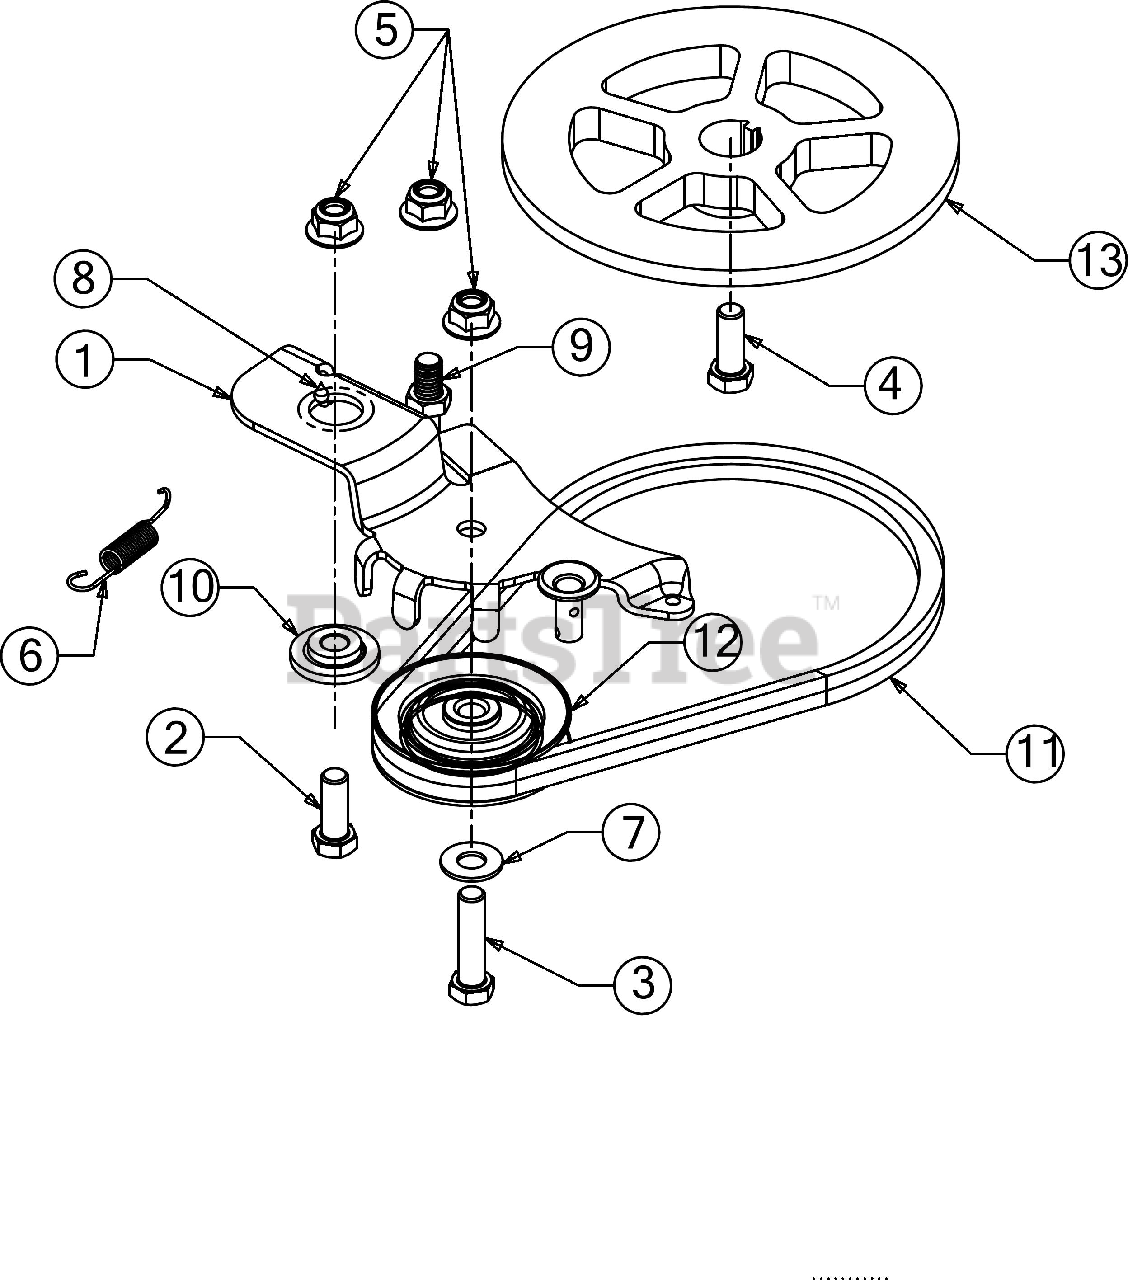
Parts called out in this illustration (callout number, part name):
1	IDLER ASSEMBLY
1	IDLER BRACKET
2	SCREW 3/8-16 X 1 GR5
3	SCREW 3/8-16 X 1.50
4	SCREW 3/8-24 X 1.00 GR5
6	SPRING
7	FLAT WASHER
8	GREASE
9	STUD: 33 X 1.75 3/8-16
10	SHOULDER SPACER
11	BELT 1/2 X 4L X 24.82
12	V-IDLER PULLEY
13	FLYWHEEL PULLEY
